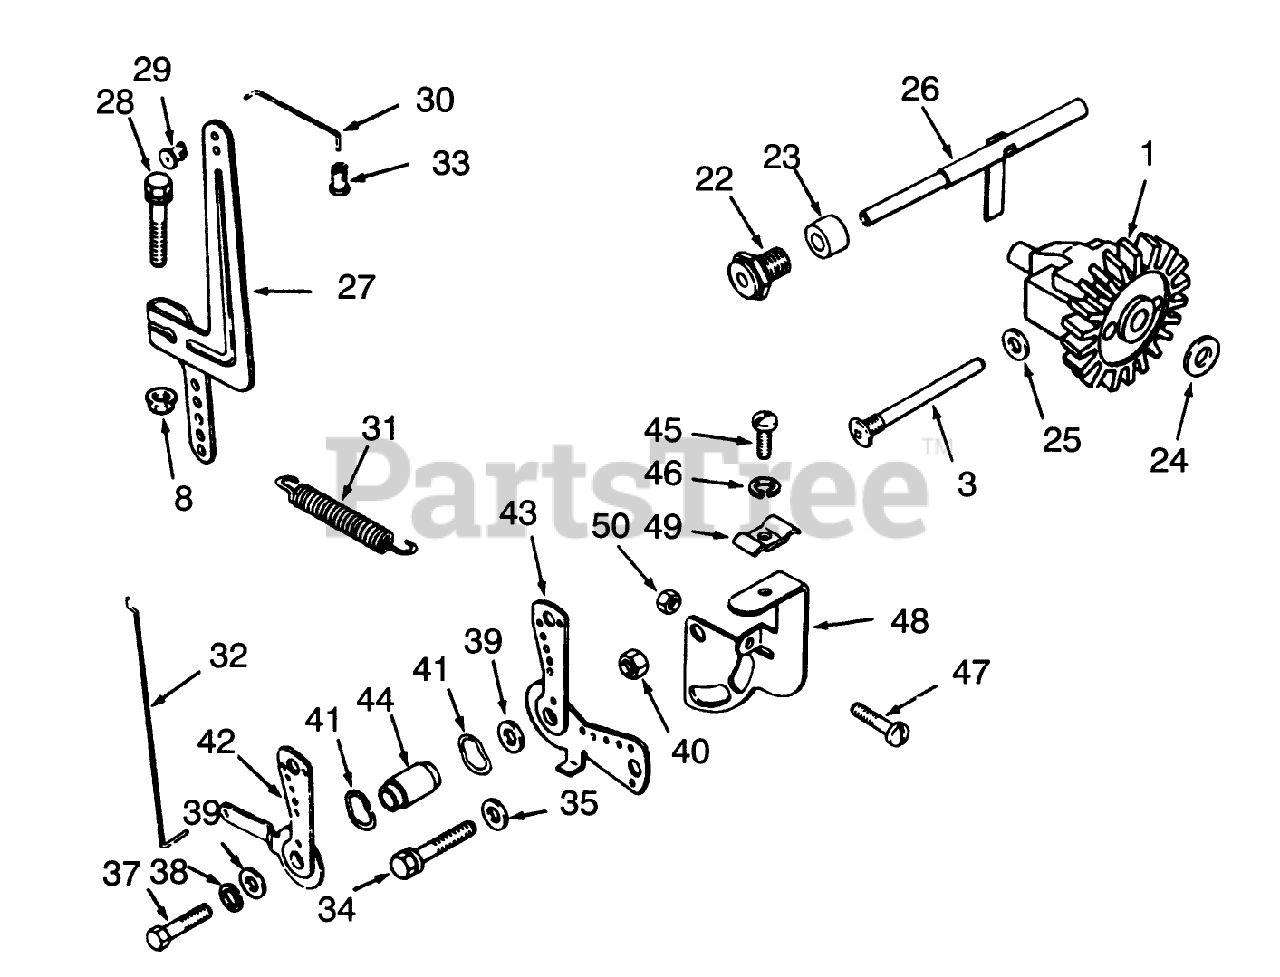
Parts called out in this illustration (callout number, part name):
1	KOHLER A-235743-5
3	KOHLER 231355
8	KOHLER X-799-1
22	KOHLER 235476
23	KOHLER X-400-80
24	KOHLER 237022
25	KOHLER 25-468-01
26	KOHLER A-235256-5
27	KOHLER 47-090-20
28	KOHLER X-776-1
29	KOHLER 47-158-07
30	KOHLER 47-079-10
31	KOHLER 47-091-01
32	KOHLER 47-079-01
33	KOHLER 25-158-09
34	KOHLER X-132-6
35	KOHLER X-25-72
37	KOHLER X-5-26
38	KOHLER X-20-1
39	KOHLER X-25-63
40	KOHLER X-76-2
41	KOHLER 275690
42	KOHLER 47-090-07
43	KOHLER 47-090-08
44	KOHLER 47-112-02
45	KOHLER X-67-51
46	KOHLER 25-468-04
47	KOHLER 232556
48	KOHLER 47-126-09
49	KOHLER 47-237-02
50	KOHLER X-72-4
